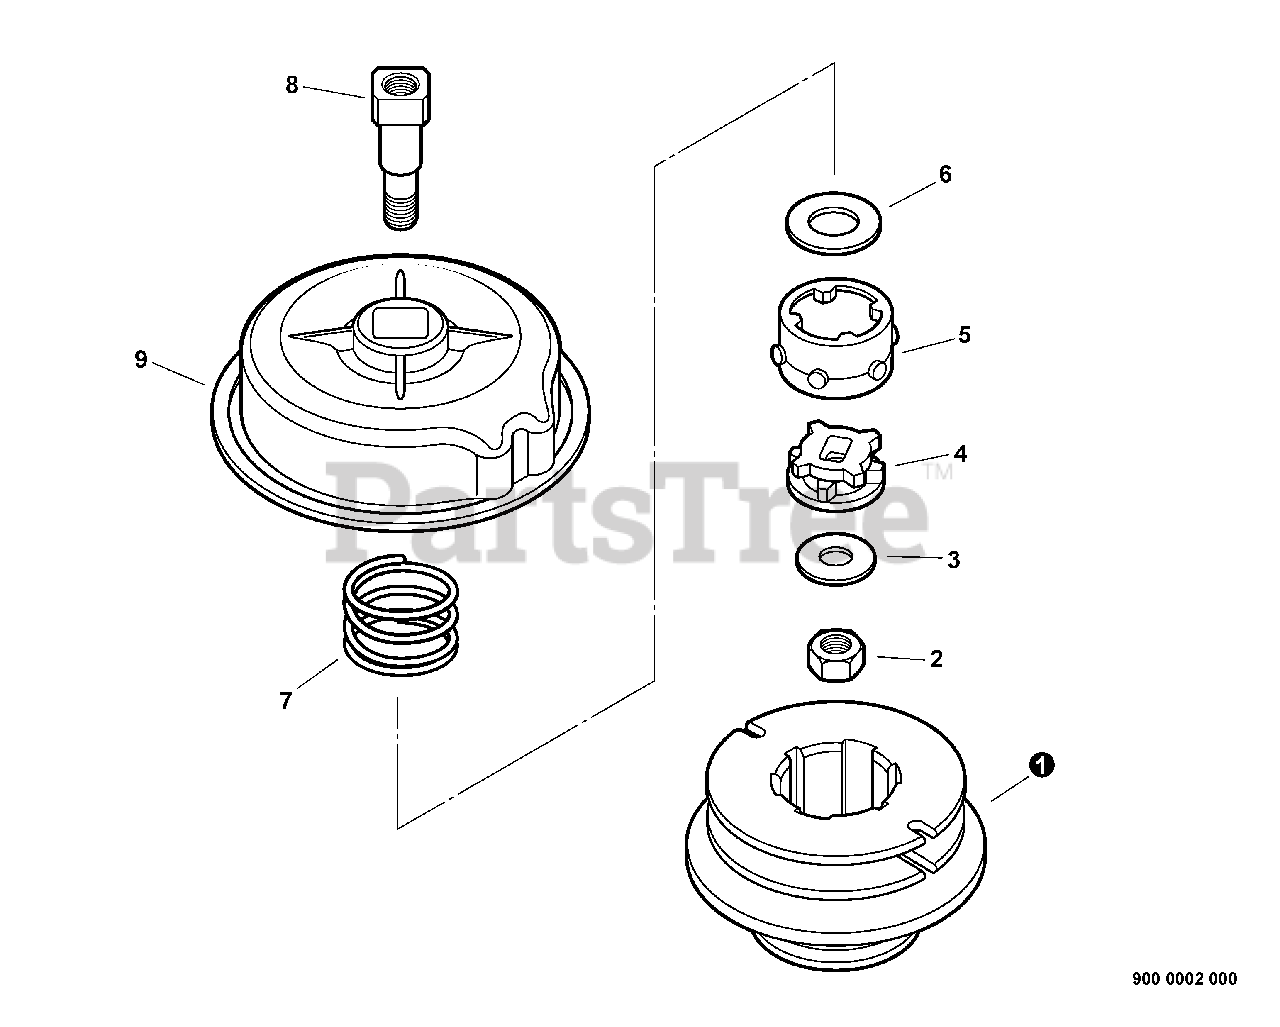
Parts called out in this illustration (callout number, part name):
2	NUT, LOCK
3	WASHER, FLAT
4	CAM, INNER
5	CAM, OUTER
6	WASHER, FLAT
8	BOLT, SHAFT 10 MM
9	HOUSING
